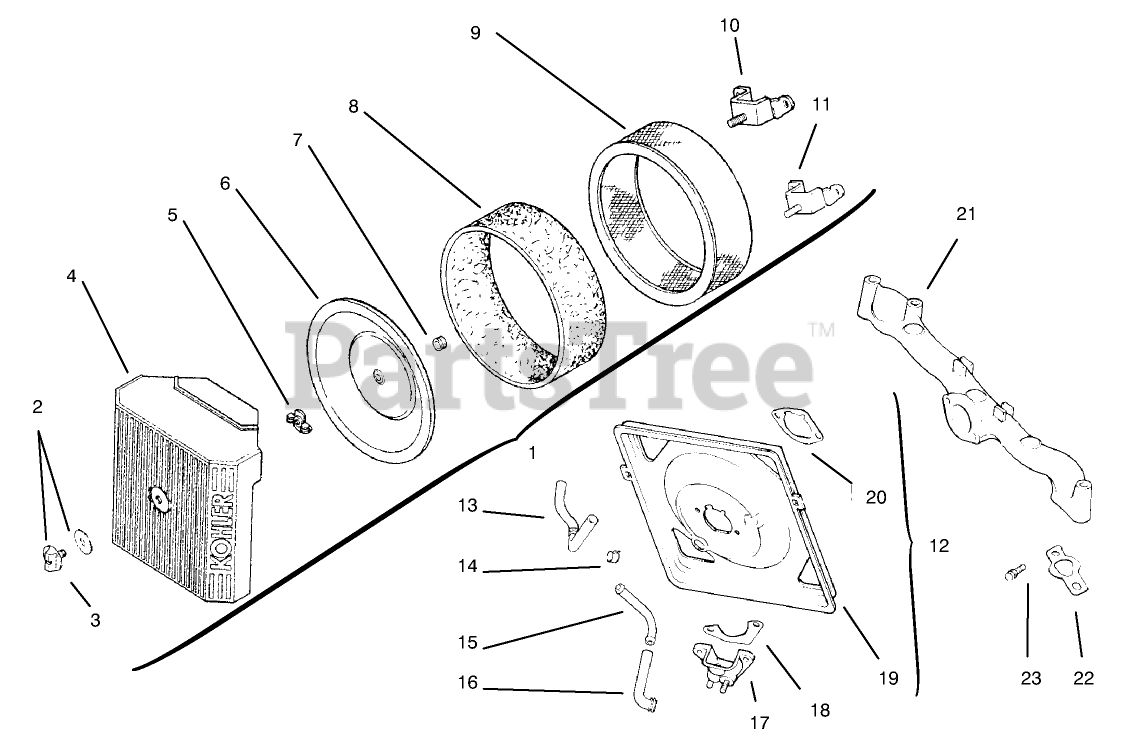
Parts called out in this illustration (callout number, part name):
1	Kit-Air Cleaner Cover
2	Kit-Knob w/Gasket
3	Knob-Cover
4	Cover-Air Cleaner
5	Nut-Wing
6	Cover-Inner Air Cleaner
7	Seal-Air Intake (Only On: 72103)
8	Element-Precleaner
9	Element-Air Cleaner
10	Bracket-Air Cleaner
11	Bracket-Air Cleaner
12	Kit-Air Cleaner Base
13	Hose-Breather
14	Clamp
15	Fitting
16	Hose-Breather
17	Cup-Fuel Spitback
18	Gasket-Fuel Spitback Cup (Only On: 72103, 72083)
19	Base-Air Cleaner
20	Gasket-A/C Base (Only On: 72103, 72083)
21	Manifold-Intake (Only On: 72103)
22	Gasket-Intake Manifold
